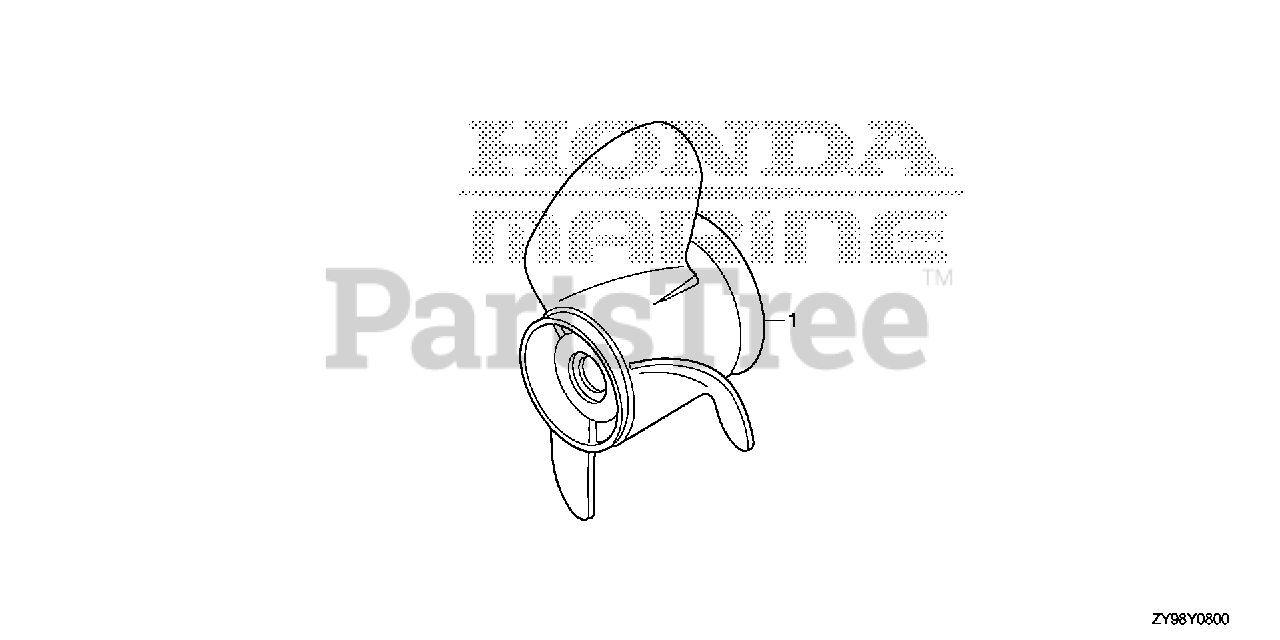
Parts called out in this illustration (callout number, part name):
1	PROPELLER, THREE-BLADE (13X19) (SUS)
1	PROPELLER, THREE-BLADE (13X21) (SUS)
1	PROPELLER, THREE-BLADE (14X11) *NH283* (AL) (STIN GRAY)
1	PROPELLER, THREE-BLADE (13-3/4X13) *NH283* (AL) (STIN GRAY)
1	PROPELLER, THREE-BLADE (13-1/2X15) *NH283* (AL) (STIN GRAY)
1	PROPELLER, THREE-BLADE (13-1/4X17) *NH283* (AL) (STIN GRAY)
1	PROPELLER, THREE-BLADE (13X21) *NH283* (AL) (STIN GRAY)
1	PROPELLER, THREE-BLADE (13X19) *NH283* (AL) (STIN GRAY)
1	PROPELLER, THREE-BLADE (13-1/4X17) (SUS)
1	PROPELLER, THREE-BLADE (13-1/4X15) (SUS/HAC)
1	PROPELLER, THREE-BLADE (13-1/4X17) (SUS/HAC)
1	PROPELLER, THREE-BLADE (13-1/4X19) (SUS/HAC)
1	PROPELLER, THREE-BLADE (13-1/4X21) (SUS/HAC)
1	PROPELLER, THREE-BLADE (13-1/2X14) *NH283* (STIN GRAY)
1	PROPELLER, THREE-BLADE (13-1/5X19) *NH283* (STIN GRAY)
1	PROPELLER, THREE-BLADE (13-1/5X21) *NH283* (STIN GRAY)
